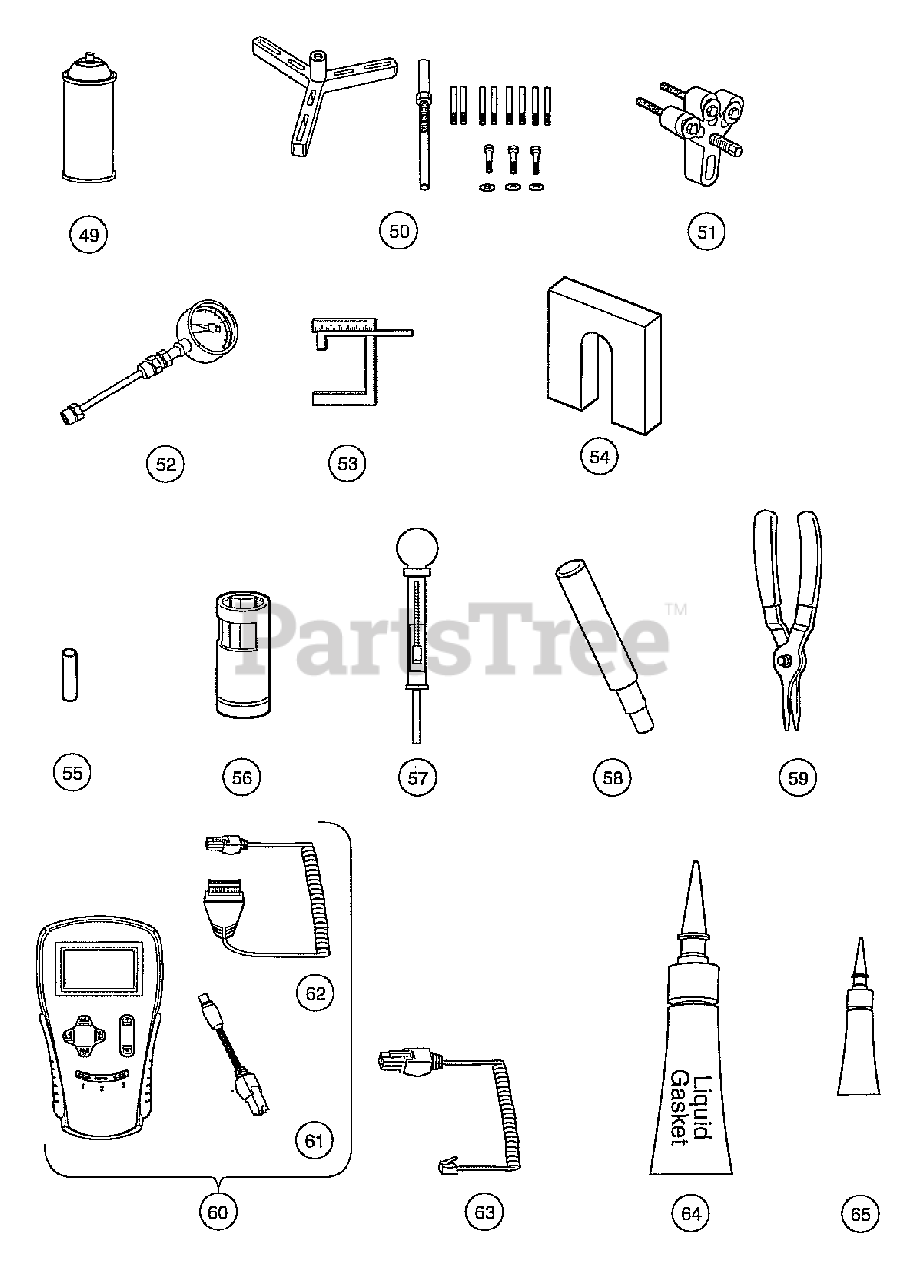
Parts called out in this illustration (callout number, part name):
49	Dry Moly Lubricant
50	Flywheel Puller
51	Flywheel Puller Kit
52	Fuel Injection Pump Pressure Tester
53	Gauge, Carburetor Float Level
55	Governor Shaft Installation Tool
56	Hydraulic Brake Adjuster
57	Hydrometer
58	Idle Gear Bushing Replacement Tool
59	Internal Retaining Ring Pliers
60	IQ Display Module (IQDM) Kit
61	Adaptor, Cable
62	IQDM Series 2 Cable
63	IQDM Series 1 Cable (replacement)
64	Liquid Gasket (transaxle case)
65	Moly-Teflon Lubricant (4-oz. (113-gram) tube)
